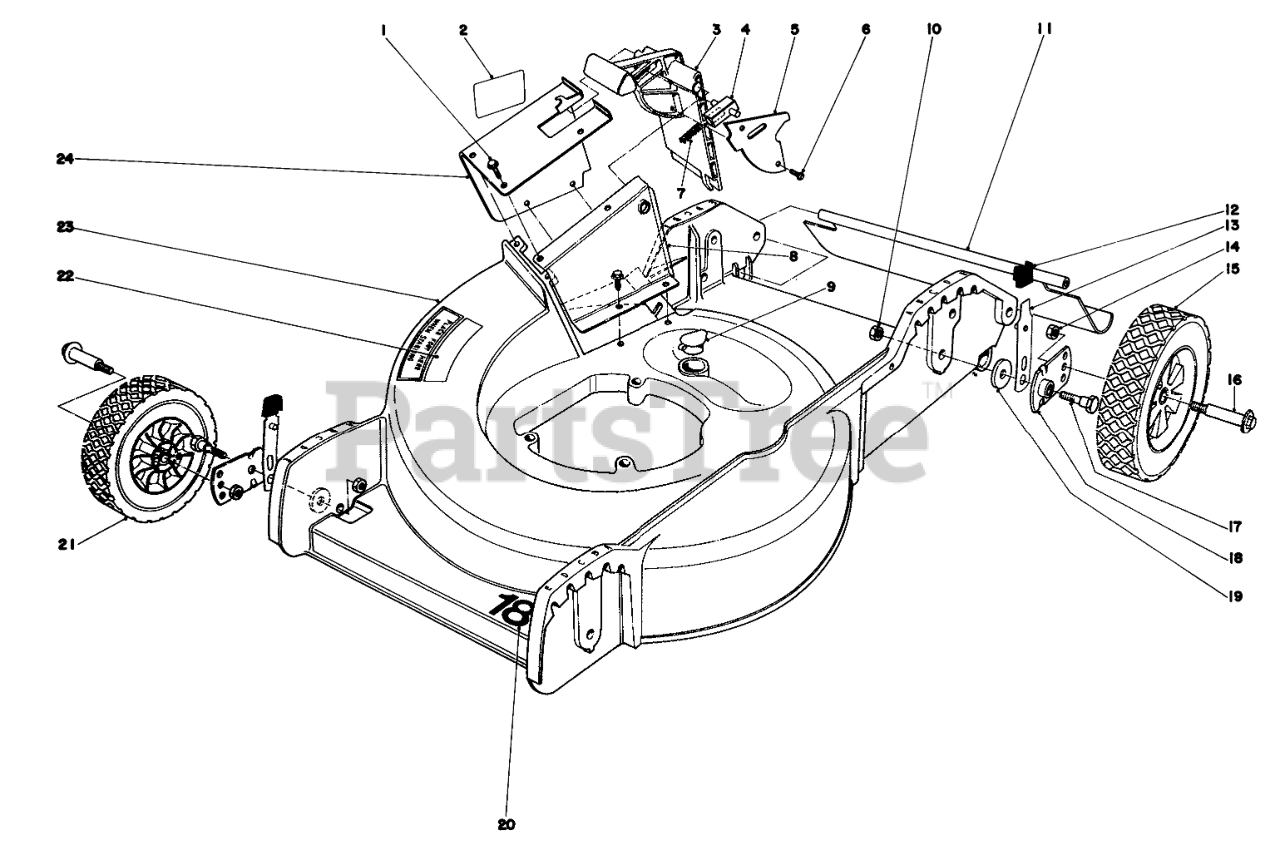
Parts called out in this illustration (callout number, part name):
1	SCREW
2	Decal-Danger
3	Door Mulching
4	Door Latch
5	Cover Door
7	SPRING-COMPRESSION, LATCH
8	Inner Tunnel
9	Plug Washout
10	Nut
11	SHIELD - TRAILING
12	KNOB-ARM
13	SPRING ARM ASM
14	Nut
15	WHEEL TIRE ASM 8 IN
16	BOLT-WHEEL
17	PIVOT SCREW
18	PIVOT ARM ASSY
19	PIVOT WASHER
20	Decal
21	WHEEL TIRE ASM 7 IN
22	Decal-Place Foot Here
23	Housing
24	Tunnel Outer
